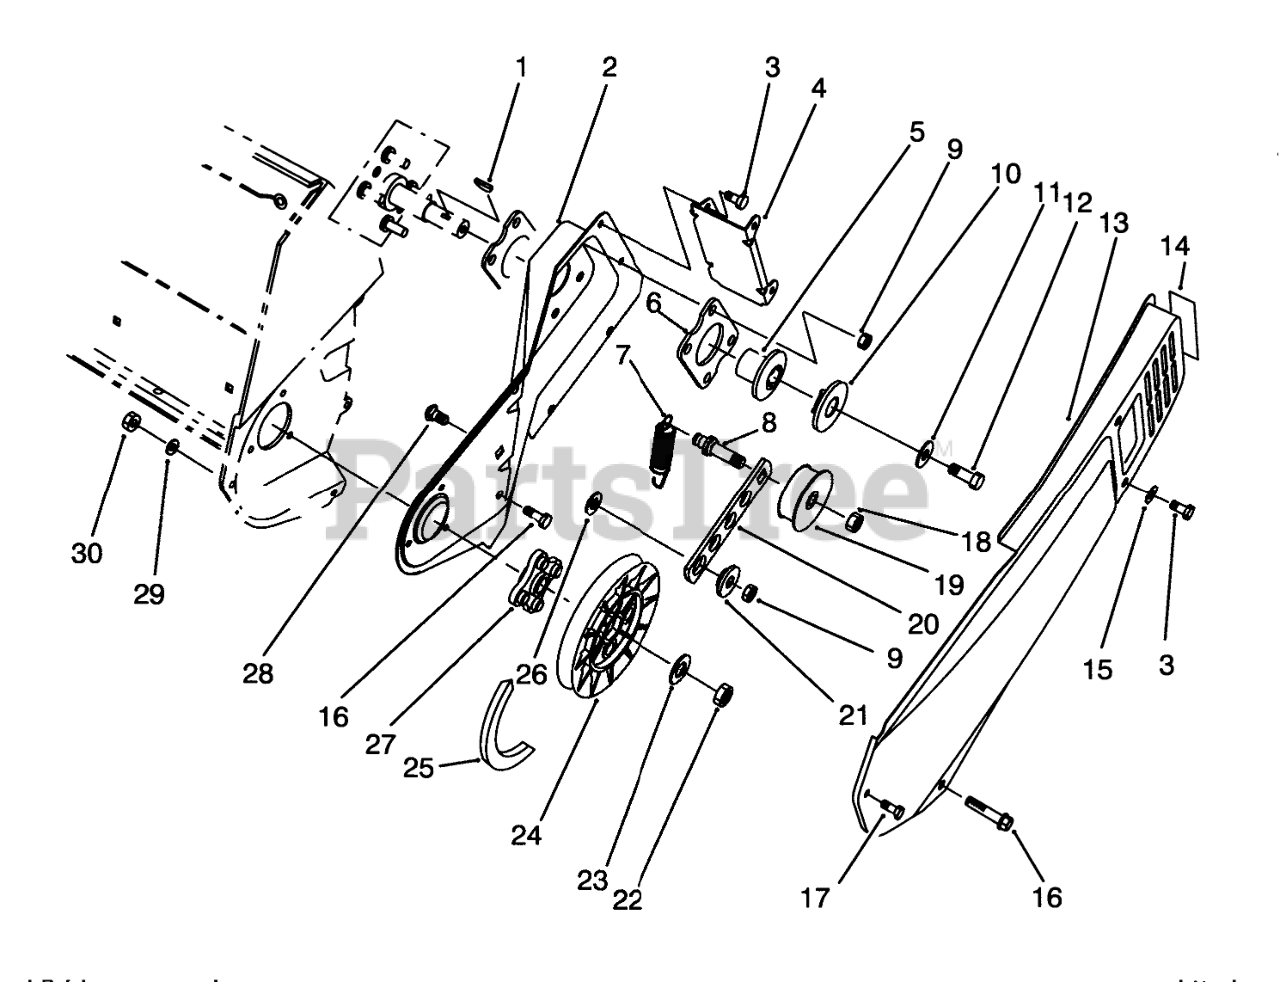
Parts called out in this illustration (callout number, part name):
1	KEY-WOODRUFF
2	Sideplate-LH
3	SCREW-HWH
4	Bracket-Cover
5	Hub-HALF SHEAVE
6	Plate Engine
7	SPRING-EXTENSION
8	PIN-IDLER
9	NUT-LOCK, NI
10	CAP-HALF SHEAVE
11	WASHER-FLAT
12	SCREW-HH
13	Cover-Belt
14	Decal-Hot
15	WASHER-FLAT
16	SCREW-PLASTIC
18	NUT-LOCK, NI
19	PULLEY-IDLER
20	ARM-IDLER
21	BUSHING-IDLER
22	NUT-LOCK, NI
23	WASHER-FLAT
24	PULLEY-DRIVEN
25	V-BELT
26	WASHER
28	SCREW-CARR
29	WASHER-FLAT
30	NUT-LOCK, NI
